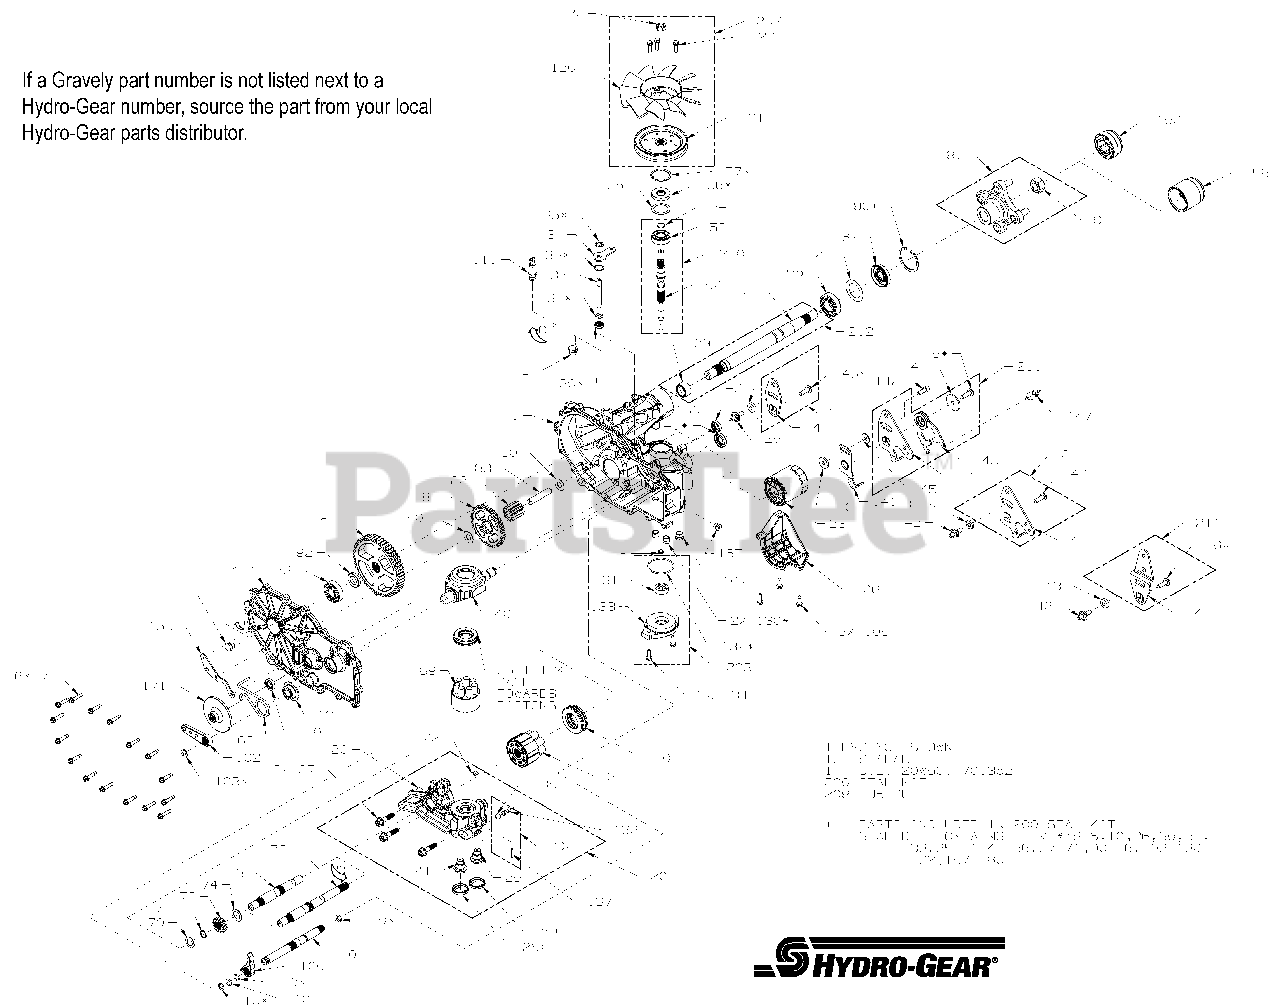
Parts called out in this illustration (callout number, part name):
7	HFHCS 1/4-20 X 1.125"
13	SEALANT, TUBE
22	PLATE, BYPASS
23	FILTER, OIL
26	SEAL, PLUG 1.250 X .250
30	SEAL, LIP .375 X .75 X .25
31	RING, RETAINING .375 EXTERNAL
33	RING, RETAINING .750 INTERNAL
34	ARM, BYPASS
35	RING, RETIANING .375 EXTERNAL
41	SEAL, LIP 12 X .0 X 7
45	WASHER, .34 X .88 X .06
46	TWHCS 5/1 6-24 X 1.00
55	WASHER, 1.23 X 1.56 X .04
56	SEAL, LIP 17 X 40 X 7
57	RING, RETAINING
60	BEARING, THRUST
64	KIT, 16cc MOTOR BLOCK
65	BEARING, THRUST BALL 30 X 52 X 13
69	ASS'Y, BLOCK 7 PISTON
70	WASHER, .63 X 1.0 X .05
71	RING, RETAINING .625
74	WASHER, .72 X 1.16 X .04
80	WASHER, .5 X 1.0 X .03
83	JACK SHAFT
90	RING, RETAINING 1.06 INTERNAL
95	BEARING, BALL 1.0 X 52 X 15 OPEN 6205M
96	SEAL, LIP TC4, 1.0 X 2.06 X .38
97	KIT, HUB, 4 BOLT
99	NUT, HEX LOCK 3/4-16
102	ARM, BRAKE 2"
105	HFHCS 1/4-20 X .75
106	GUARD, FILTER, LH
111	FITTING, STR 9/16-18 SAE .5 BARB
122	NUT, HEX JAM 1/2-20 W/PATCH
131	GEROTOR ASSEMBLY
132	O-RING, -137, .103 X 2.050
134	HFHCS 1/4-20 X .75
140	SPACER, .320 X 1.005 X .179
141	ARM, NEUTRAL LEFT
142	SHCS 5/16-24 X 10
147	SPRING, EXTNSN RTN
200	KIT, SEAL
201	KIT, CENTERSECTION, LH, CHRG
203	KIT, CHARGE PUMP
207	KIT, FAN/PULLEY
209	HUB, PULLER, UNIVERSAL
210	KIT, INPUT SHAFT
211	KIT, RTN, CCW
